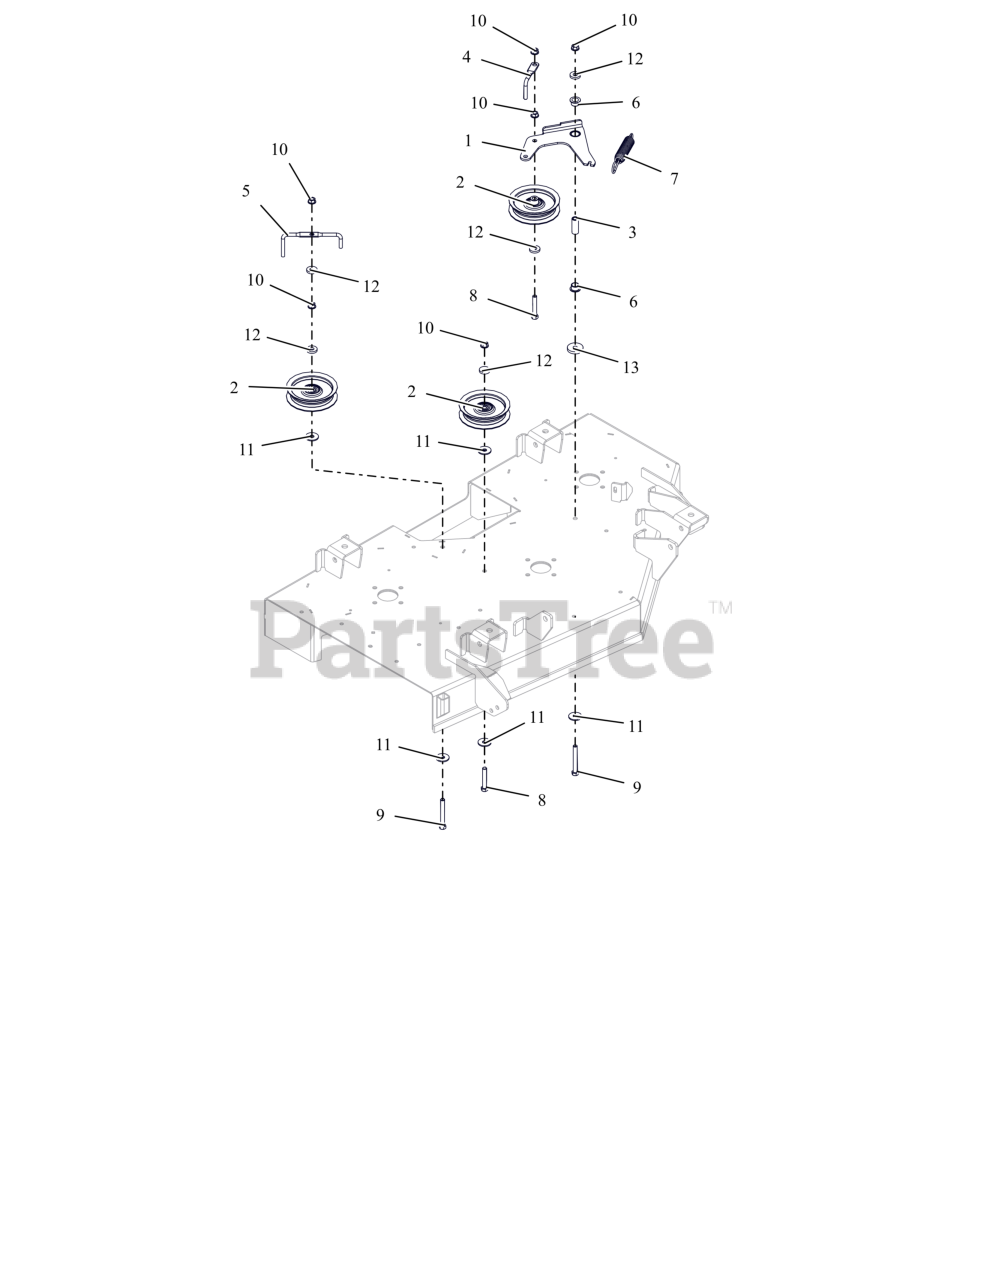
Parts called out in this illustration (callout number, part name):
1	WLDMT, IDLER ARM-42"
2	IDLER, FLAT - 4.06" X .75"
3	SPACER, .375IDX.625ODX1.66 PM
4	WIREFORM-BELT FINGER
5	BELT FINGER
6	BSHG-FLG, .625X.750X.500X1.00
7	SG-TENS .135X.98X6.0 WLD 62
8	BLT,HEX .38-16X2.25 G5 ZCC
9	BLT, HEX .38-16X3.00F G5 ZCC
10	NUT-LK-CTR-FLG .375-16 GF ZCC
11	WSHR FL STL .406X1.25X.10ZC120
12	WSHR, FLT .406X1.00X.188 ZCC
13	WSHR, FLT .406X1.50X.245 ZCC
